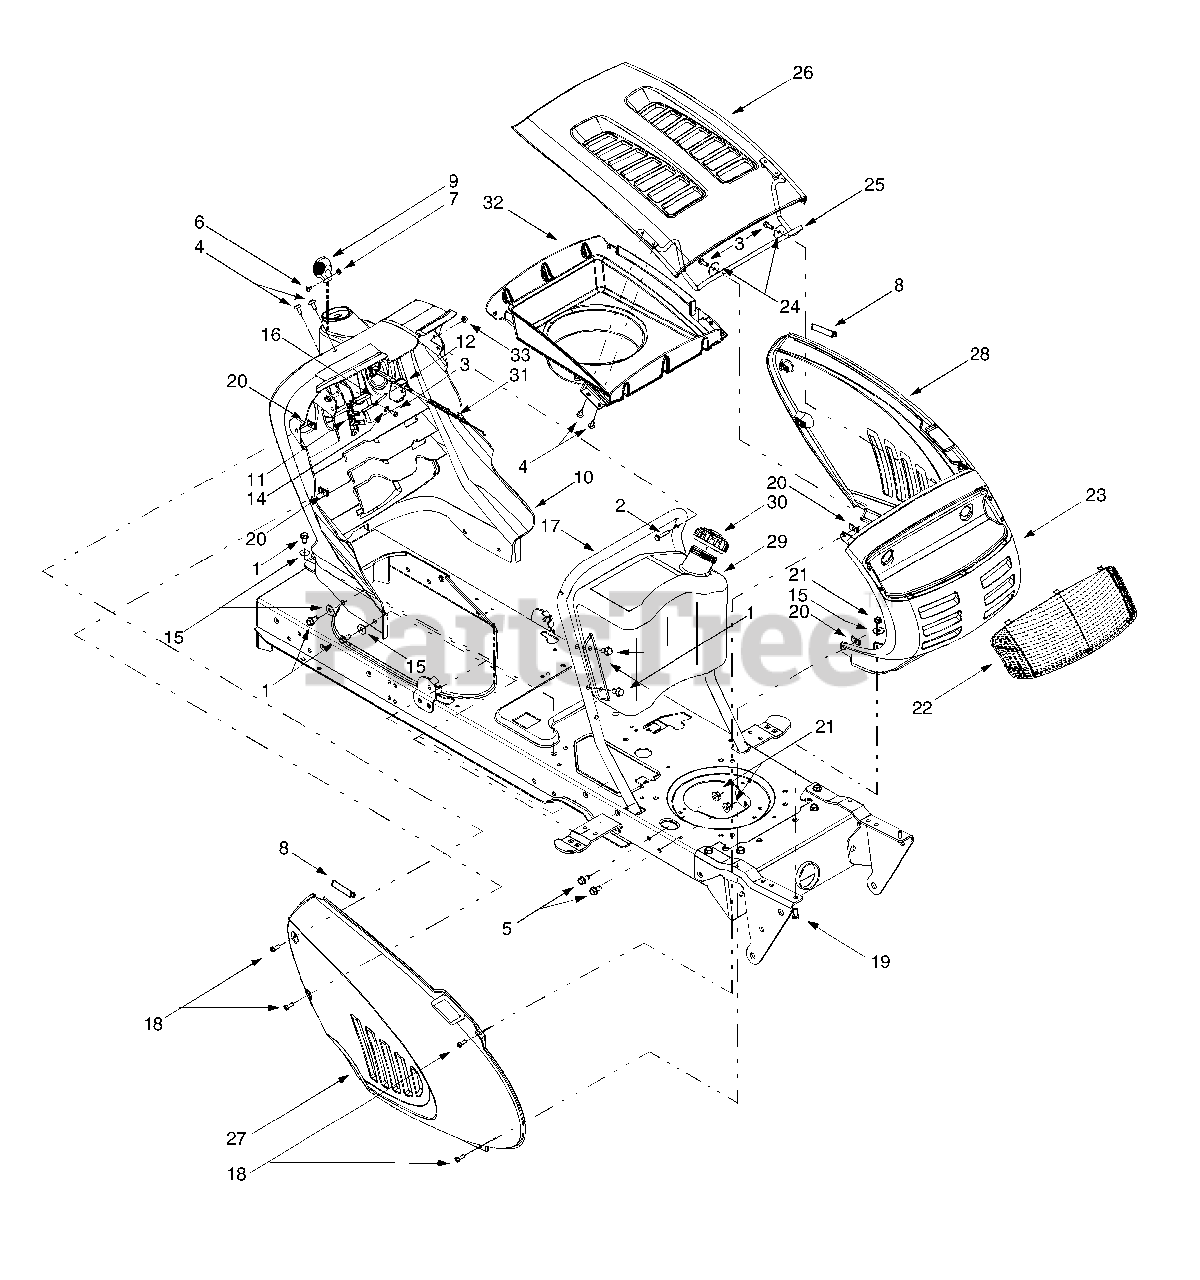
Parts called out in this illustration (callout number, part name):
1	Self-tapping Screw, 5/16-18 x .625
2	Self-tapping Screw, 1/4-20 x 1.0
3	Self-tapping Screw, 1/4-15 x .75
4	Torx Self-tapping Screw, 5/16-18 x .625
5	Screw, 5/16-18 x .875 (Grade 5)
6	Torx Screw, #8-32 x .375
7	Hex Nut, 8-32
8	Five-inch Trim Strip
9	Throttle Control Lever
10	Dash Panel
11	Plastic Plug
12	Parking Brake Button
14	Flat Washer, .281 x .5 x .063
15	Flat Washer, .349 x 1.0 x .063
16	Pivot Rod
19	Hex Cap Screw, 5/16-18 x .75
20	U-type Speed Nut, 1/4-20
21	Flange Lock Nut, 5/16-18
22	Lens, 9-style
23	Grille, 9-style
24	Flat Washer, .285 x 1.25 x .08
25	Hood Hinge Rod
30	Fuel Cap (Fits Either Tank)
31	Choke Knob/Cable Assembly (Units w/ B&S Opposed Twin or OHV Twin)
32	Hood Plenum (Units w/ B&S OHV V-Twin)
33	Hex Flange Lock Nut, 1/4-20
